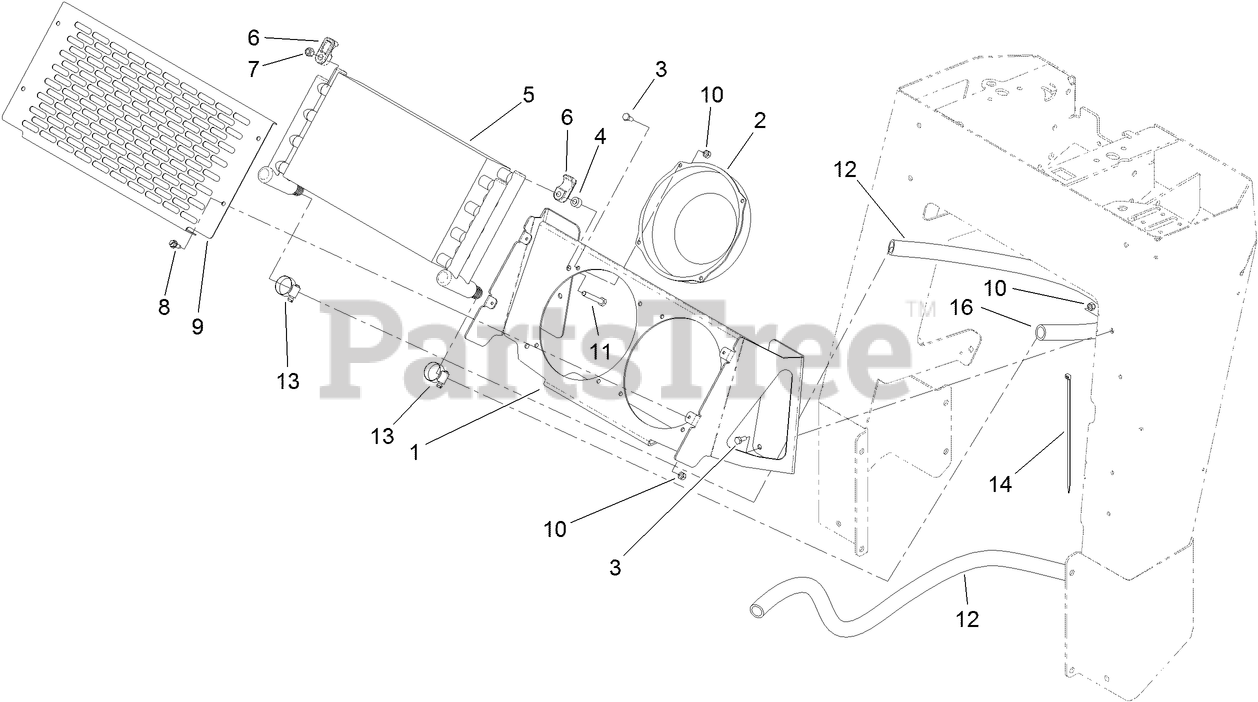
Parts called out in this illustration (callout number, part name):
1	MOUNT-COOLER
3	SCREW-HH
4	SPACER
5	COOLER-OIL
6	CLAMP-COOLER, OIL
7	NUT-LOCK, NI
8	SCREW-HWH
9	COVER-COOLER
10	NUT-LOCK, NI
11	SCREW-HH
12	HOSE-RETURN
13	CLAMP-HOSE
14	TIE-CABLE
16	HOSE-COOLER
